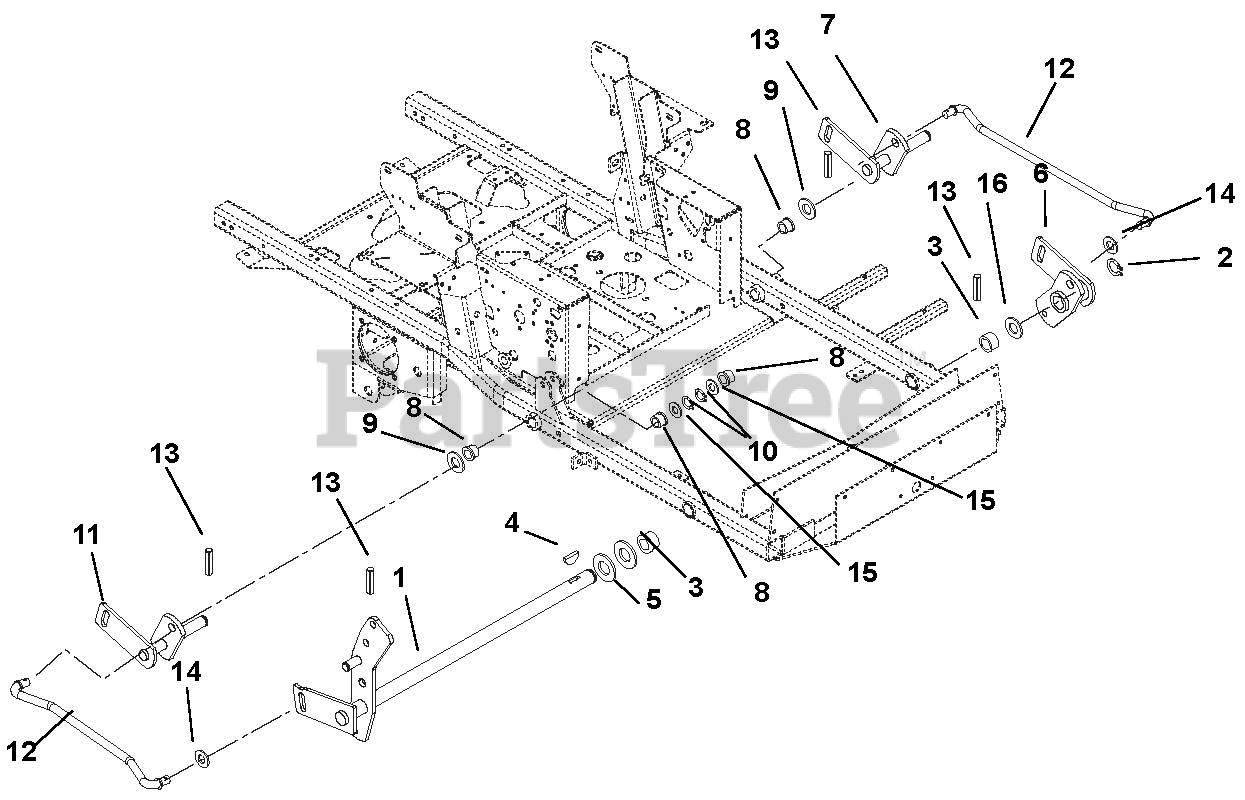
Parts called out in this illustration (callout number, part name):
1	Lift, Hydraulic Mower
2	Ring, Retaining External 1.00 x .078
3	Bushing, 1.00 x 1.12 x .75 x 1.375
4	Key, Woodruff .25 x 1.00
5	Washer, Flat Steel 1.062 x 2.00 x .134
6	Weldment, Lift Arm Front
7	Weldment, Rear Lift Arm Left Hand
8	Bushing, Flange Nylon .762 x 1.00 x .58 x 1.48
9	Washer, Hardened Steel .758 x 1.23 x .031
10	Ring, Retaining External .689 x .077
11	Weldment, Right Hand Rear Lift Arm
12	Rod, Lift Assist
13	Pin, Roll .250 x 1.25 Stainless Steel
14	Washer, Flat Steel .630 x 1.25 x .062
15	Washer, Flat Steel .812 x 1.50 x .135
16	Washer, Hardened Thrust 1.00 x 1.55 x .03
